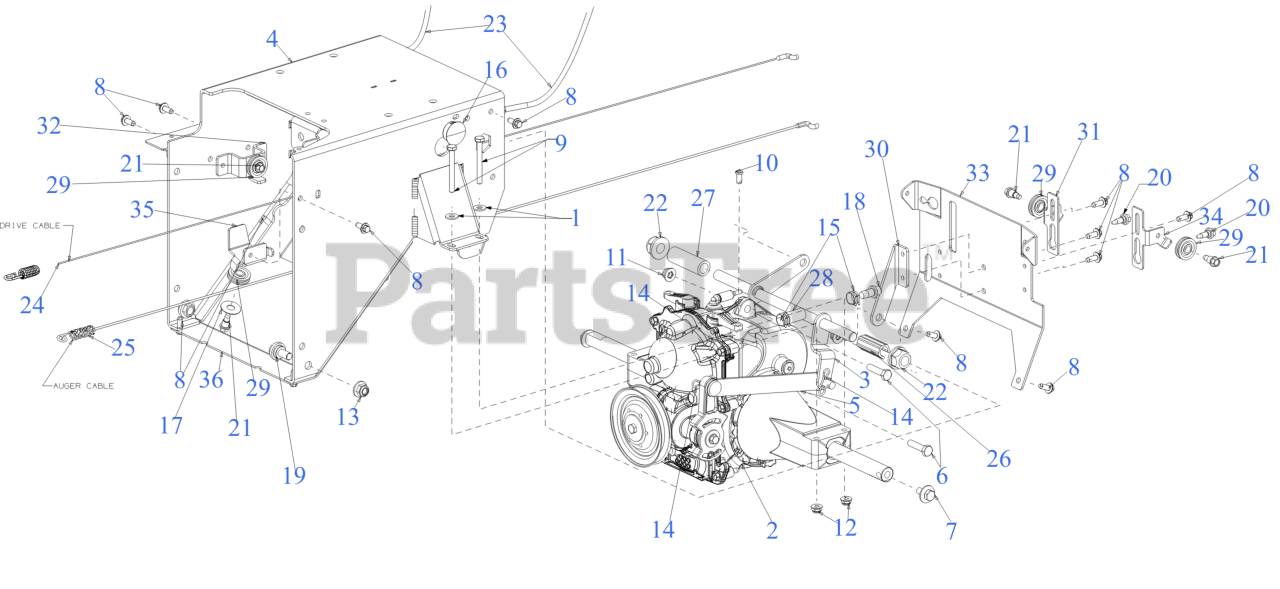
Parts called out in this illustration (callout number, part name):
1	FLAT WASHER 1/4 SAE ZINC
2	HYDRO TRANSMISSION ASSEMBLY
3	CONTROL SHAFT ASSEMBLY
5	SHIFT LINKAGE
6	SCREW 5/16-18 x 1.25 GR5
7	SCREW 5/16-24 x .750 GR5
8	SCREW M6-1 x .625
9	SCREW 1/4-20 x 2.25 GR5
10	CLEVIS PIN-1/4X1/2
11	FLANGE LOCK NUT 5/16-18
12	FLANGE LOCK NUT
14	BOW TIE COTTER PIN 1/4-5/16
15	HOSE CLAMP
16	PLASTIC PLUG
17	FLAT WASHER
19	SHOULDER SCREW .625X.165X3/8-16
20	SHOULDER SCREW
21	SHOULDER SCREW
22	FLANGE BEARING
23	STEERING CABLE
24	WHEEL DRIVE CABLE 48.31"
25	CBL:CLU:AUGER:48.237 LG
26	SPACER-.491 ID x 1.67 LG
27	SLEEVE SPACER .525 x .78 x 2.36
28	FUEL HOSE LOW PERMEATION 11"
29	CABLE GUIDE ROLLER
31	CABLE IDLER BRACKET (RH)
34	CABLE IDLER BRACKET (LH)
